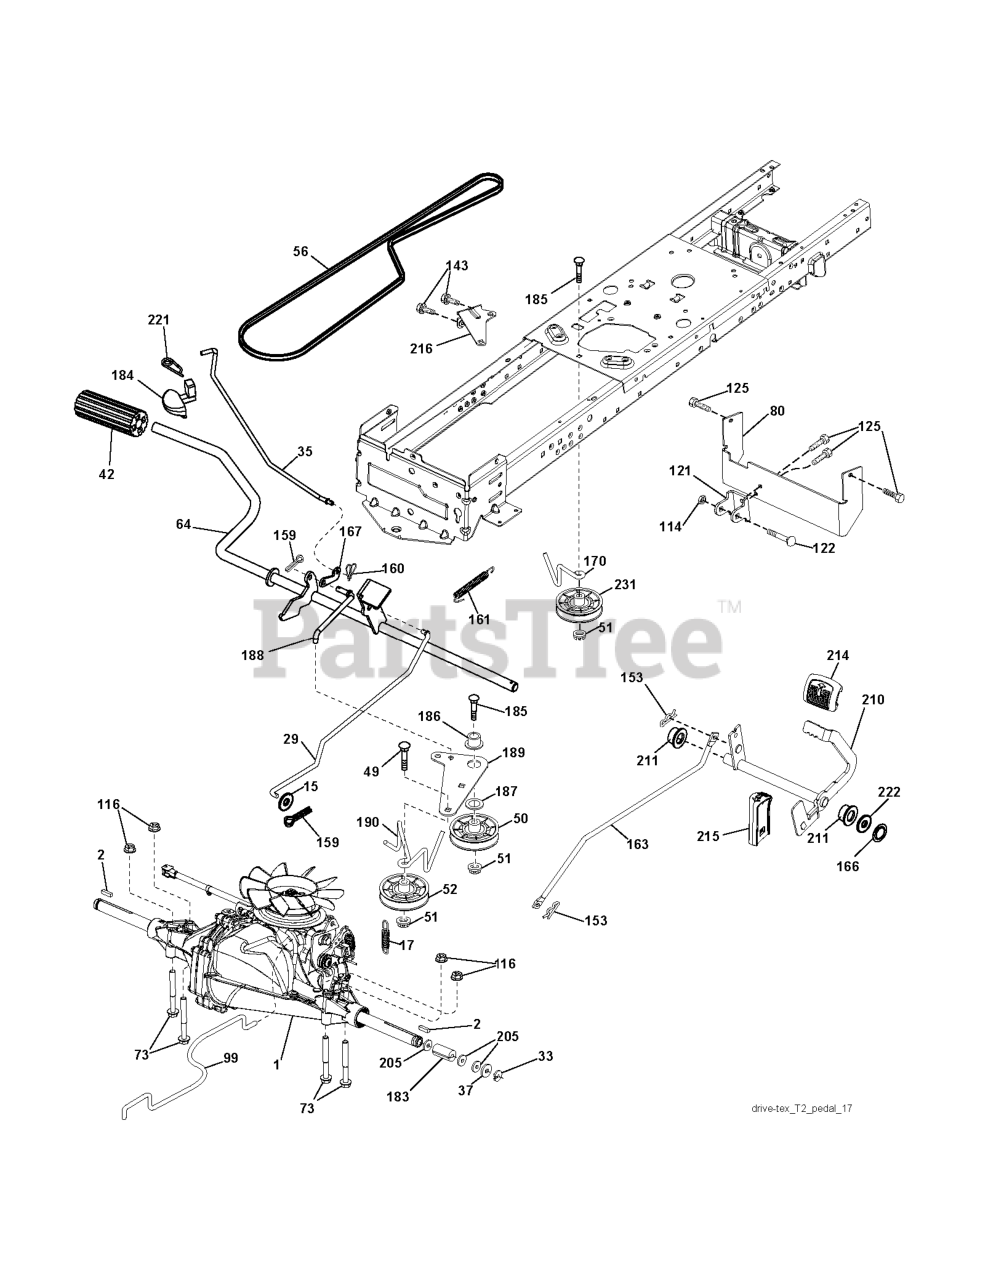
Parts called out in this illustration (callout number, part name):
2	SQUARE KEY
15	WASHER
17	SPRING.BRAKE.HG3000/3500
29	ROD.BRAKE.T2.TEX
35	ROD.CNTRL.PARK.PREDATOR.LT.TEX
42	PEDAL COVER T
50	IDLER.FLAT.910.OFFSET
51	NUT LOCK FLG 3/8-16 UNC
52	IDLER.V-GROOVE.910.OFFSET
64	SHAFT.ASM.PEDAL.BRK.CNTR
73	BOLT HEX 5/16-18 GR 5
80	RP.STRAP.TORQUE.FS.T2
99	ROD.ASM.BYPASS.SPRING.T2.FS
114	NUT.71038.31-18.HEX.NYLOCK
116	NUT LOCK HEX FLANGE 5/16-18
121	BRACKET STRAP TORQUE
122	BOLT.5/16-18X2.5
125	SCREW
143	Screw 5/16-18 x 1/2 Hex, Self Tapping 5/16-18 x 1/2
153	RETAINER M
159	COTTER PIN
160	RETAINER CLIP
161	SPRING, RETURN LT
163	ROD.CONTROL.PCH.T2.TEX
166	NUT.PUSH.625
167	LATCH.BRAKE.SPRING
170	KEEPER.CENTER SPAN.1.688
183	SPACER, AXLE PVST
184	HANDLE PARKING BRAKE
186	SPACER.RETAINER
187	WASHER 12/32X2X10GA
188	RP.LINK.CLUTCH.GROUND.DRIVE
189	BELLCRANK.GROUND.DRIVE.TEX.
190	KEEPER.BELLCRANK.DRIVE
210	ROCKER.ASM.PEDAL.CONTR
211	BEARING.NYLON
214	PEDAL.FORWARD.PAD.TEX
215	PEDAL.REVERSE.TEX.GT.4
216	BRACKET.PULLEY.IDLER.W/TEX
221	RETAINER.SPRING.CLIP.H
222	WASHER 21/32 X 1-1/4 X 10 GA.
231	IDLER.V-GROOVE.1.688.OFFSET
